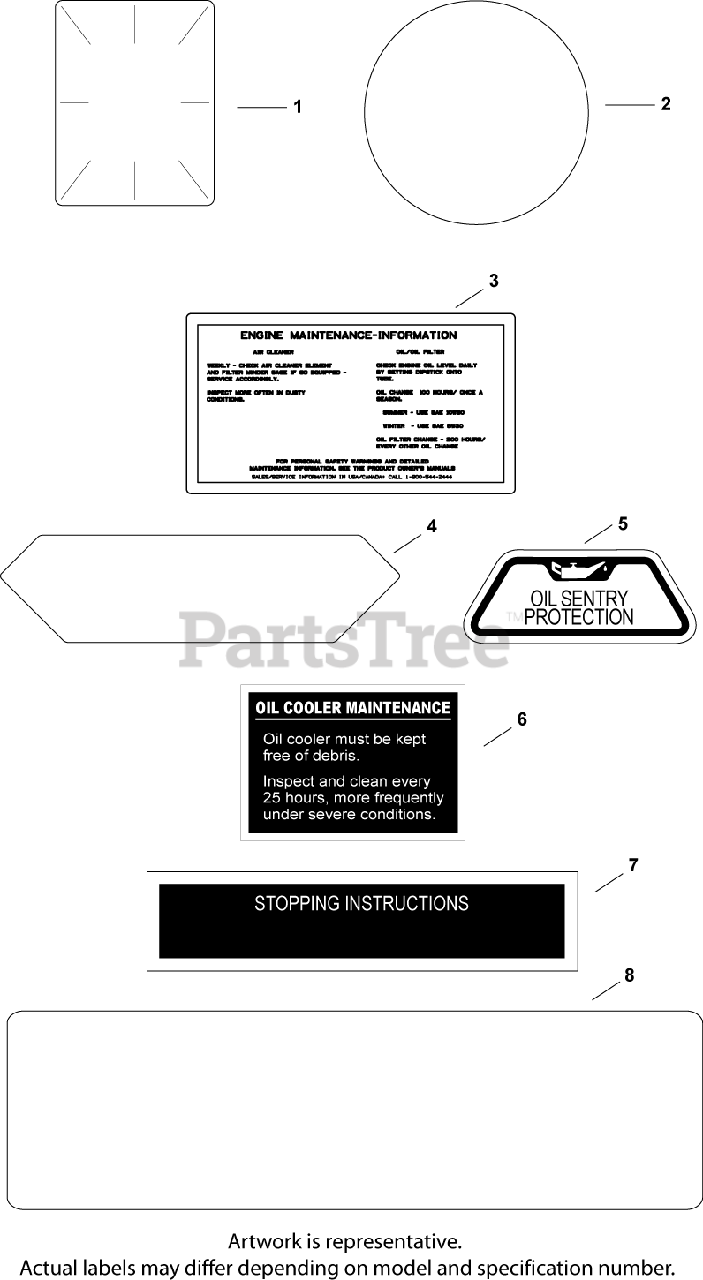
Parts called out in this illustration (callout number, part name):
1	DECAL, CLEAR LAMINATE USE 25 113 70-S
2	LABEL, (ROUND KOHLER GOLD)-USE 24 113 18
3	DECAL, OIL COOLER - (#DSC)
4	DECAL, AIR FILTER COVER
5	DECAL, OIL SENTRY - (#DSC)
6	DECAL, AIR CLEANER - (#DSC)
7	DECAL, STOPPING INSTRUCTION
8	DECAL, 27 HP
